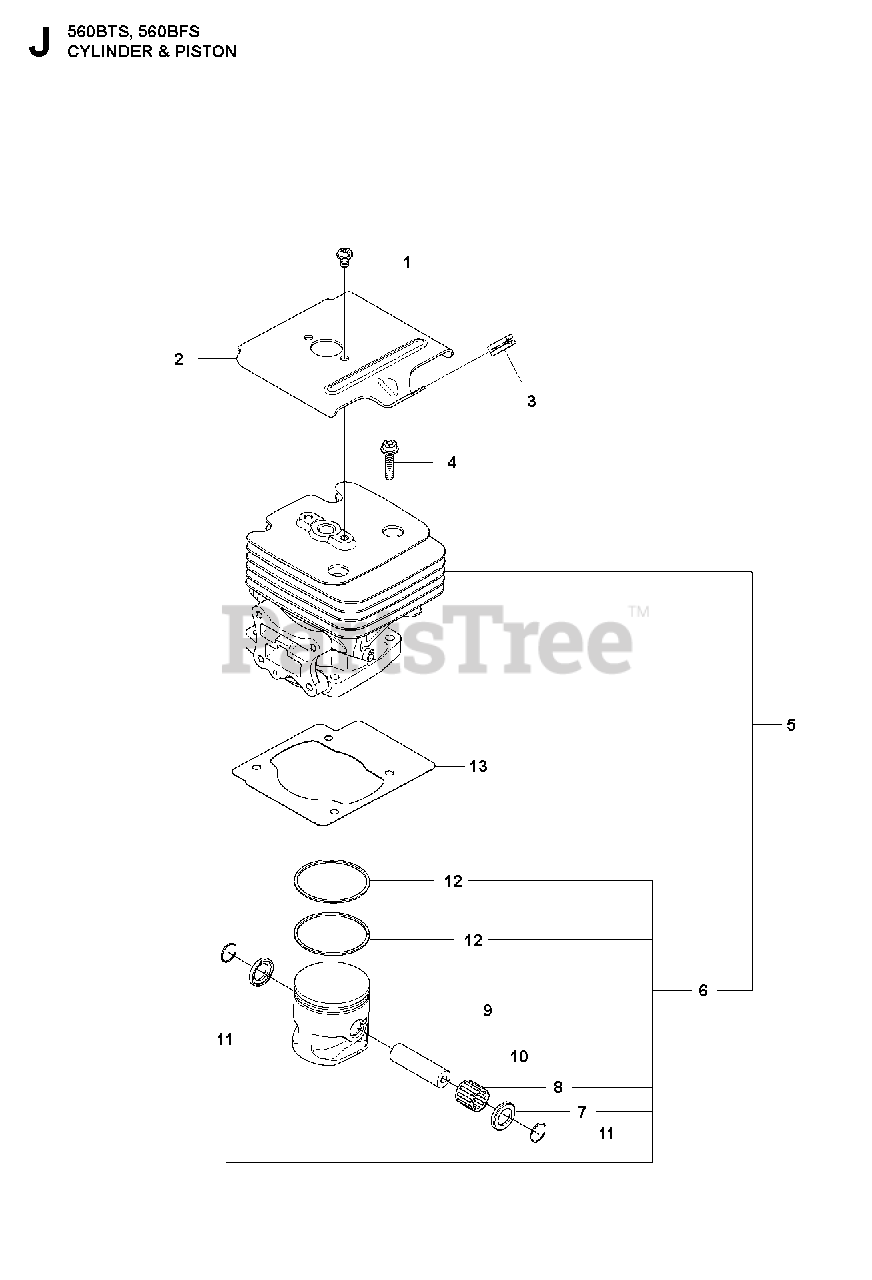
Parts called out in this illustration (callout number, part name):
5	CYLINDER ASSY
6	PISTON ASSY
7	WASHER
8	BEARING
9	PISTON
10	PIN
11	SNAP RING
12	RING
